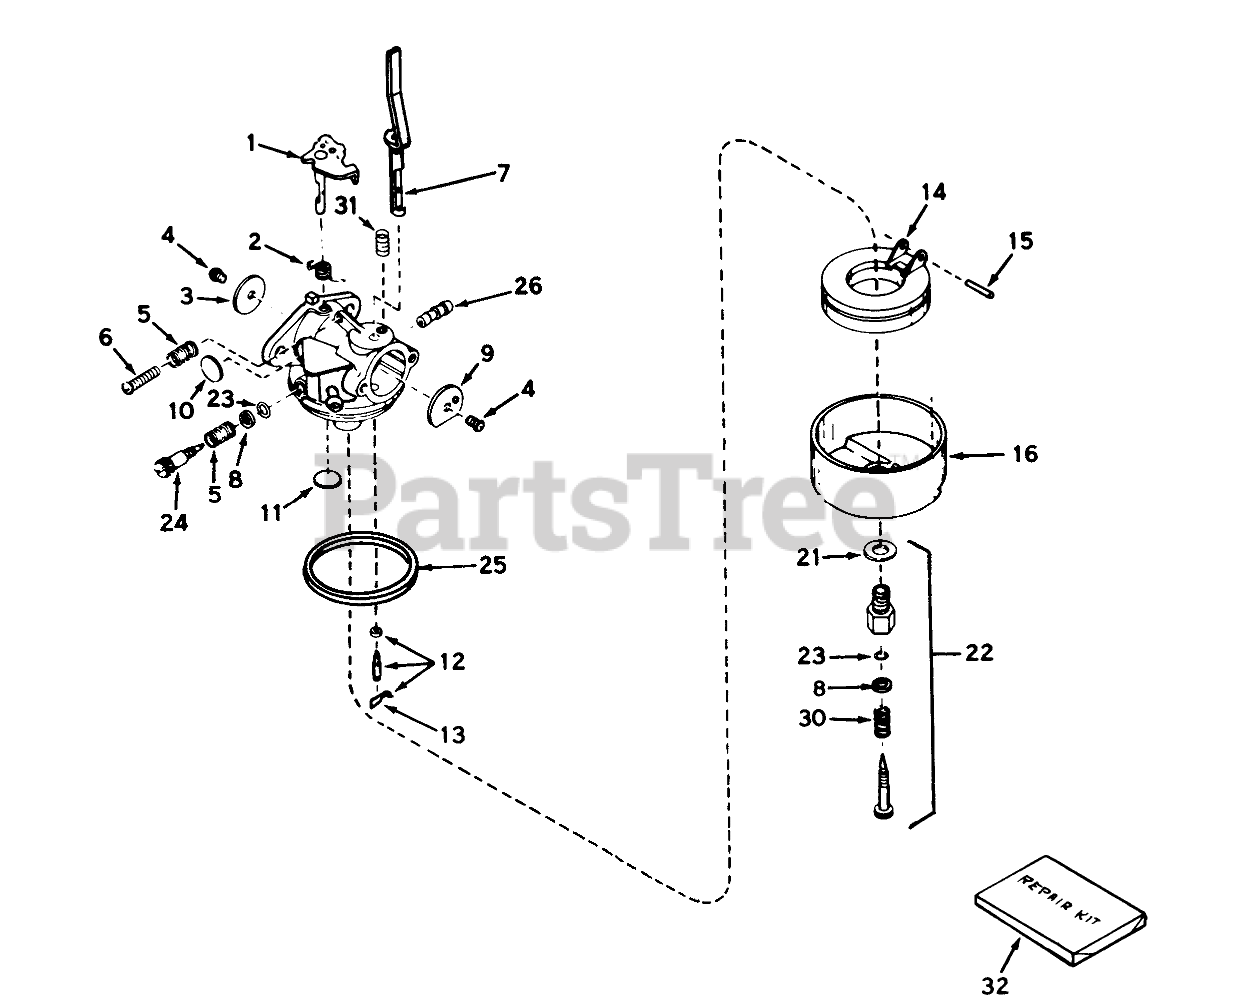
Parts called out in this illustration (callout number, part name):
1	Shaft/Lever-Throttle
2	Spring, Return
3	Shutter-Throttle
4	Screw-Shutter
5	Spring-Tension
6	Screw-Throttle Crack Screw / Idle Speed
7	Shaft & Lever Assy., Choke
9	Shutter-choke
10	Plug-Welch, Idle Mixture Well
11	Plug-Welch, Atmospheric Vent
12	Inlet Needle, Seat & Clip Assy. (Incl. Ref. #13)
13	Clip-Spring
14	Float
15	Shaft-Float
16	Bowl-Float (no drain)
21	Washer-Bowl Nut
22	Adjustment Screw Assy., Main (Incl. Ref. #8, 21, 23 & 30)
23	"O"Ring
24	Screw, Idle Adj.
25	O Ring-Bowl, Float
26	Fuel Fitting
31	Spring-Positioning, Choke
32	Kit-Repair
